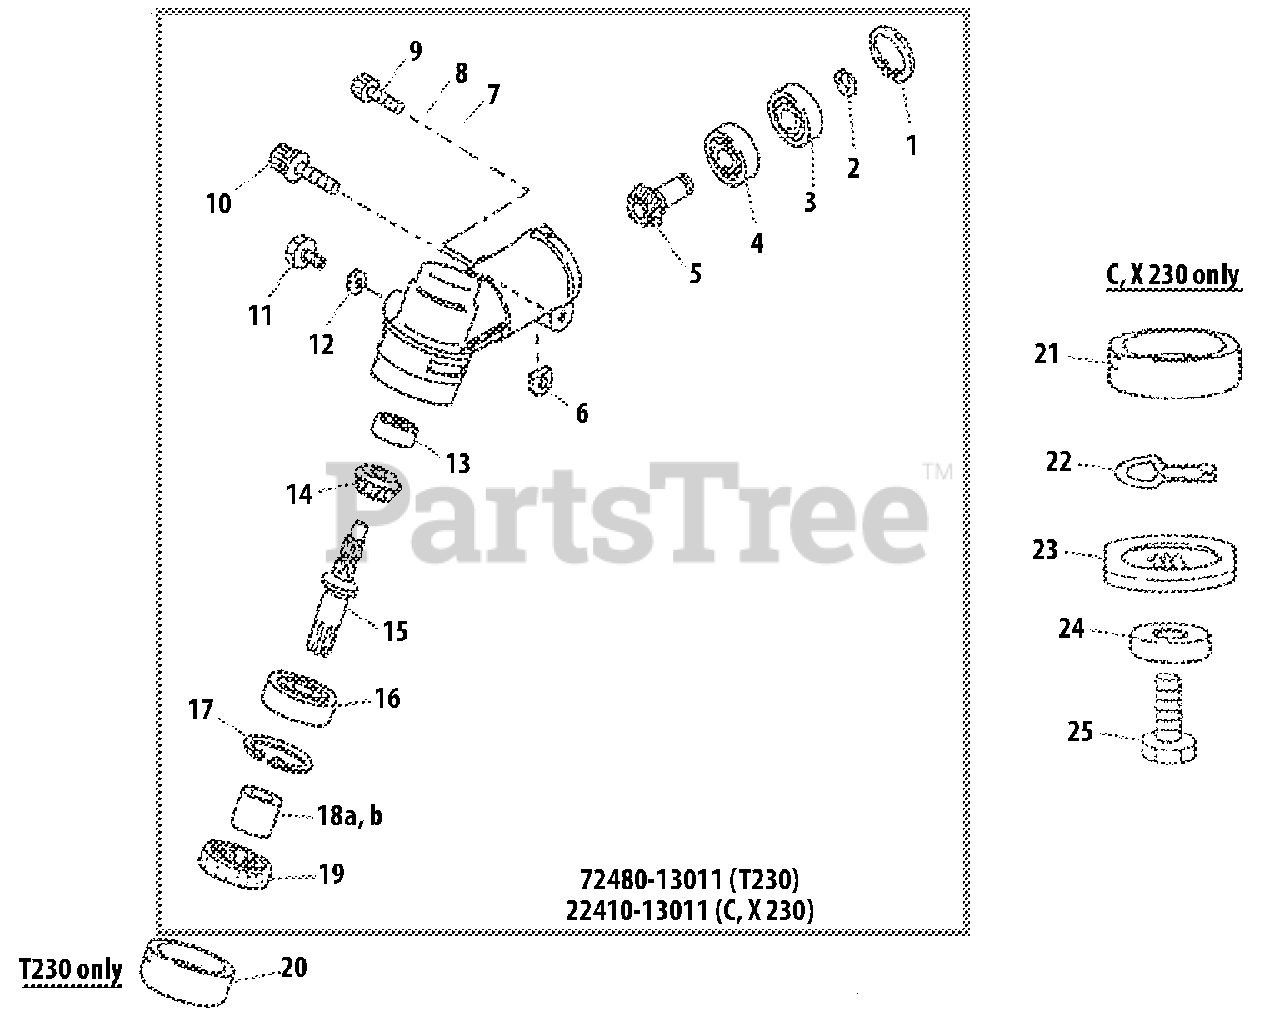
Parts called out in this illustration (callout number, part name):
1	RING, SNAP Ø22
2	RING, SNAP
3	BEARING, BALL 608ZZ
4	BEARING, BALL 608
5	GEAR, PINION
6	D-WASHER
7	WASHER, FLAT 5.5×10×0.8
8	WASHER, SPRING 5
9	BOLT 5×12
10	BOLT M5×25
11	BOLT M6×10
12	WASHER
13	BEARING, BALL 626 DDU
14	GEAR, BEVEL
15	SHAFT, GEAR
16	BEARING, BALL 6000
17	RING, SNAP Ø26
18	COLLAR
18	SPACER
19	SEAL, OIL
20	HOLDER
21	PLATE, ADAPTOR - UPPER
22	CLIP, BLADE
23	PLATE, ADAPTOR - LOWER
24	GUARD, BOLT
25	BOLT M7×18
22410-13011	GEAR CASE ASSY
72480-13011	GEAR CASE ASSY
